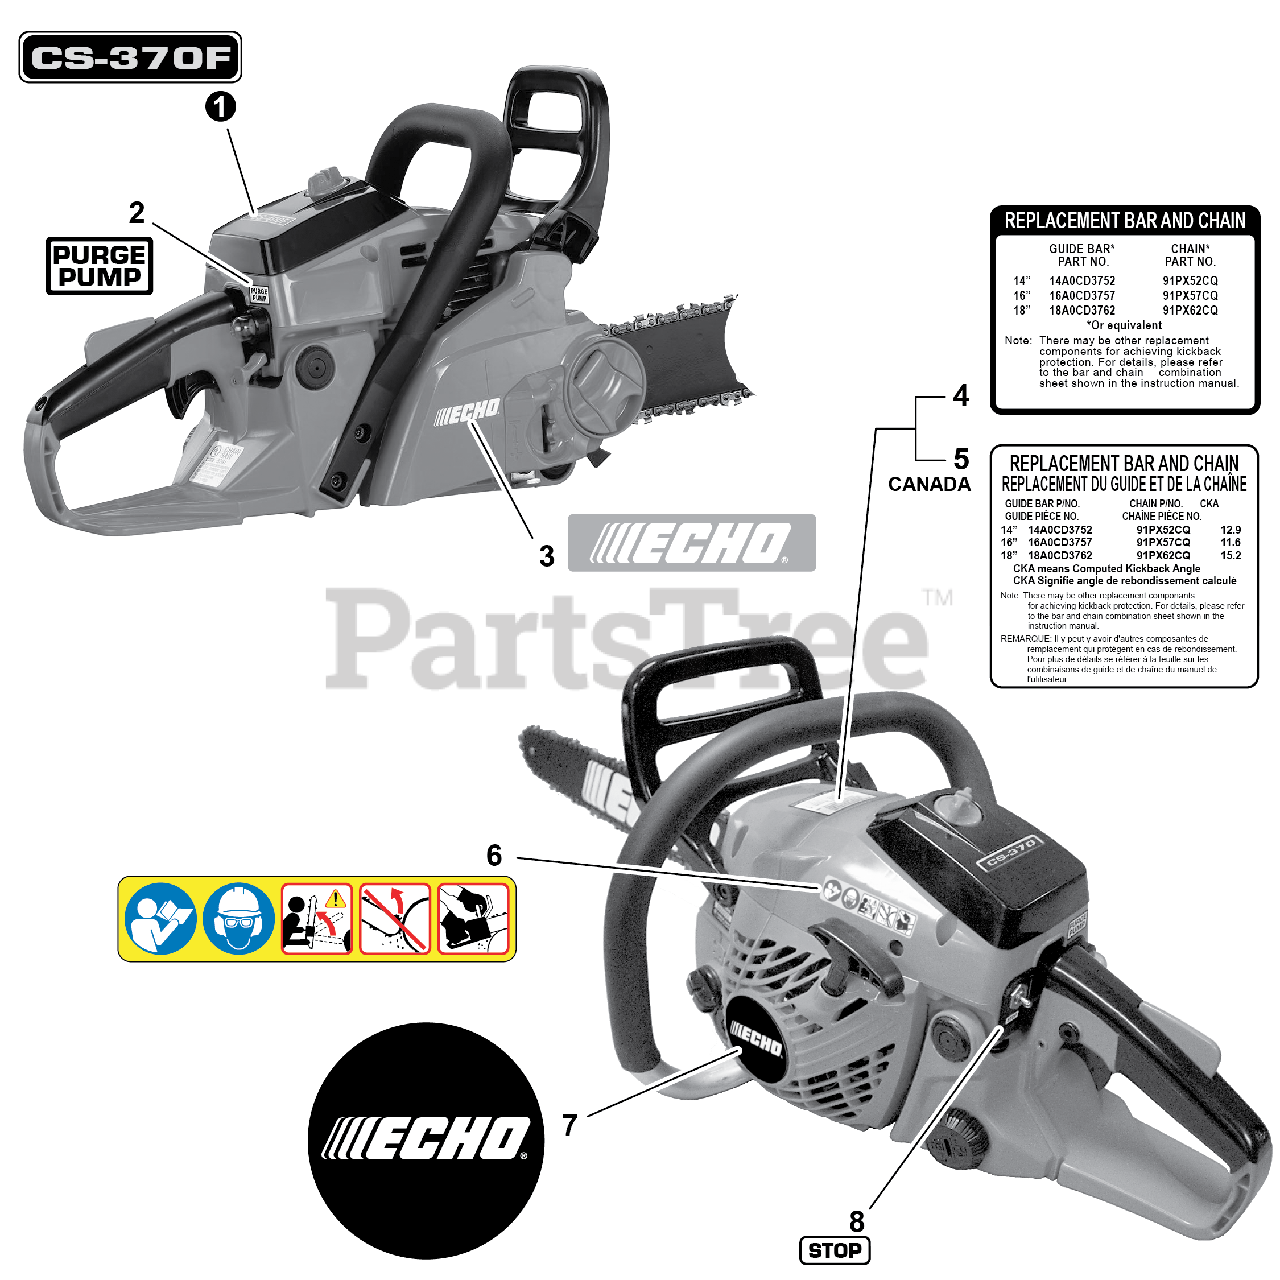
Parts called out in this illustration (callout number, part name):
1	LABEL - MODEL CS-370F
2	LABEL, PURGE PUMP
3	LABEL, ECHO
4	LABEL, BAR & CHAIN
5	LABEL, BAR & CHAIN - CANADA
6	LABEL, CAUTION
7	LABEL, ECHO
8	LABEL, STOP
